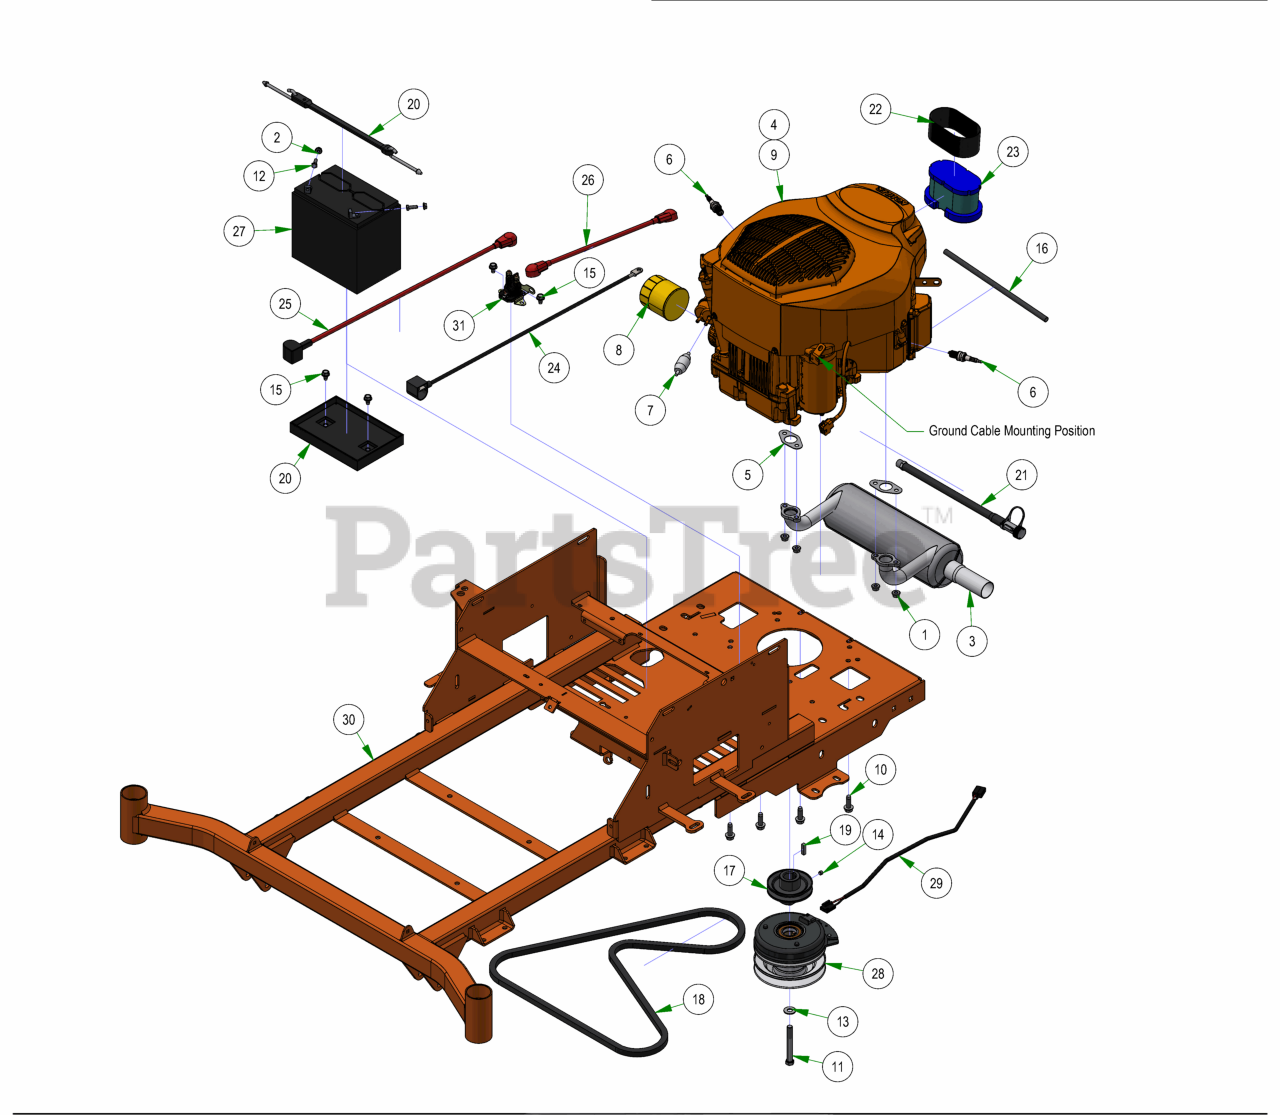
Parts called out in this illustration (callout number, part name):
1	M8 Nut Connects the 015-1012-00 and the 015-8240-00
2	1/4-20 HEX SERRATED FLANGE NUT HARD/ZINC
3	Kohler Muffler
4	KT745 Kohler Engine
5	Exhaust Gasket
6	Spark Plug
7	25/26 HP Kohler Fuel Filter
8	25 HP Kohler Oil Filter ZT?MZ
9	KT726-3013 Kohler Engine 1" Shaft
10	3/8-16 X 1-1/8 HEX WASHER UNSLOT SERRATED (TRI-LOB) TRS ZINC YELLOW
11	7/16-20 x 3 1/2" Hex Bolt GR8 W/ Patch
12	1/4-20 X 3/4 HEX CAP SCREW (GR.5) ZINC
13	3/8 FLAT WASHER USS (1" OD) ZINC
14	5/16-24 X 1/4 SOCKET SET SCREW (CUP PT) PLAIN
15	5/16-18 X 1/2 HWH unslot (F) tcs zinc
16	Braided Heat Shielding, 12"
17	3-3/4" Motor Pulley
19	1/4 X 1 SQ MACHINERY KEY 1018 STL PLN
20	2023 Battery Hold Down Assembly
21	Kohler Oil Drain
22	25/26 HP Koh Precleaner ZT/MZ
23	25/26 HP Koh Air Filter ZT/MZ
24	24 inch Black Cable – MZ/ZT
25	24" Red Battery Cable
26	14" Red Battery Cable
27	SP-35 Battery
28	120 Ft Lb. Clutch - 1" Shaft
29	Clutch Pigtail
30	2025 MZ-Avenger 54-60 Frame
